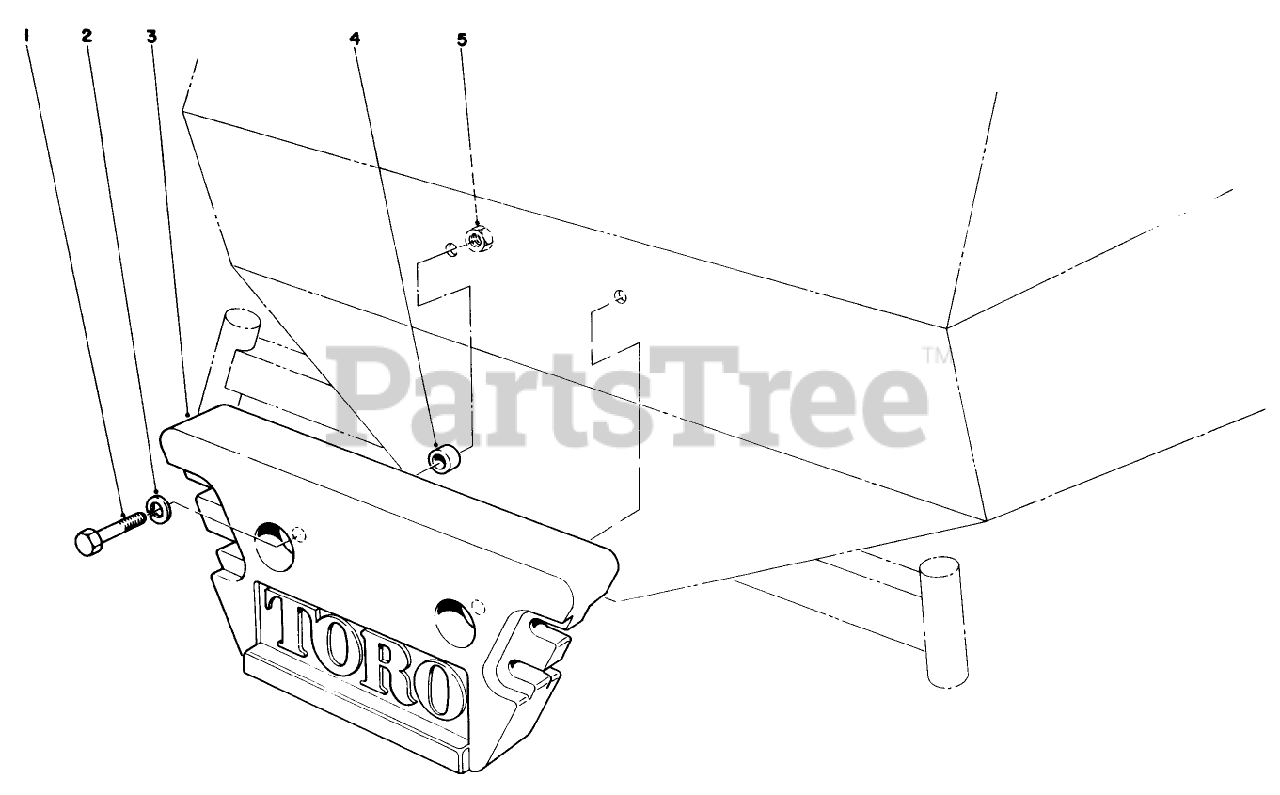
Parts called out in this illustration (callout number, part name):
1	SCREW-HH
2	WASHER-LOCK
3	WEIGHT-REAR
4	SPACER-TUBULAR
5	NUT-HH
